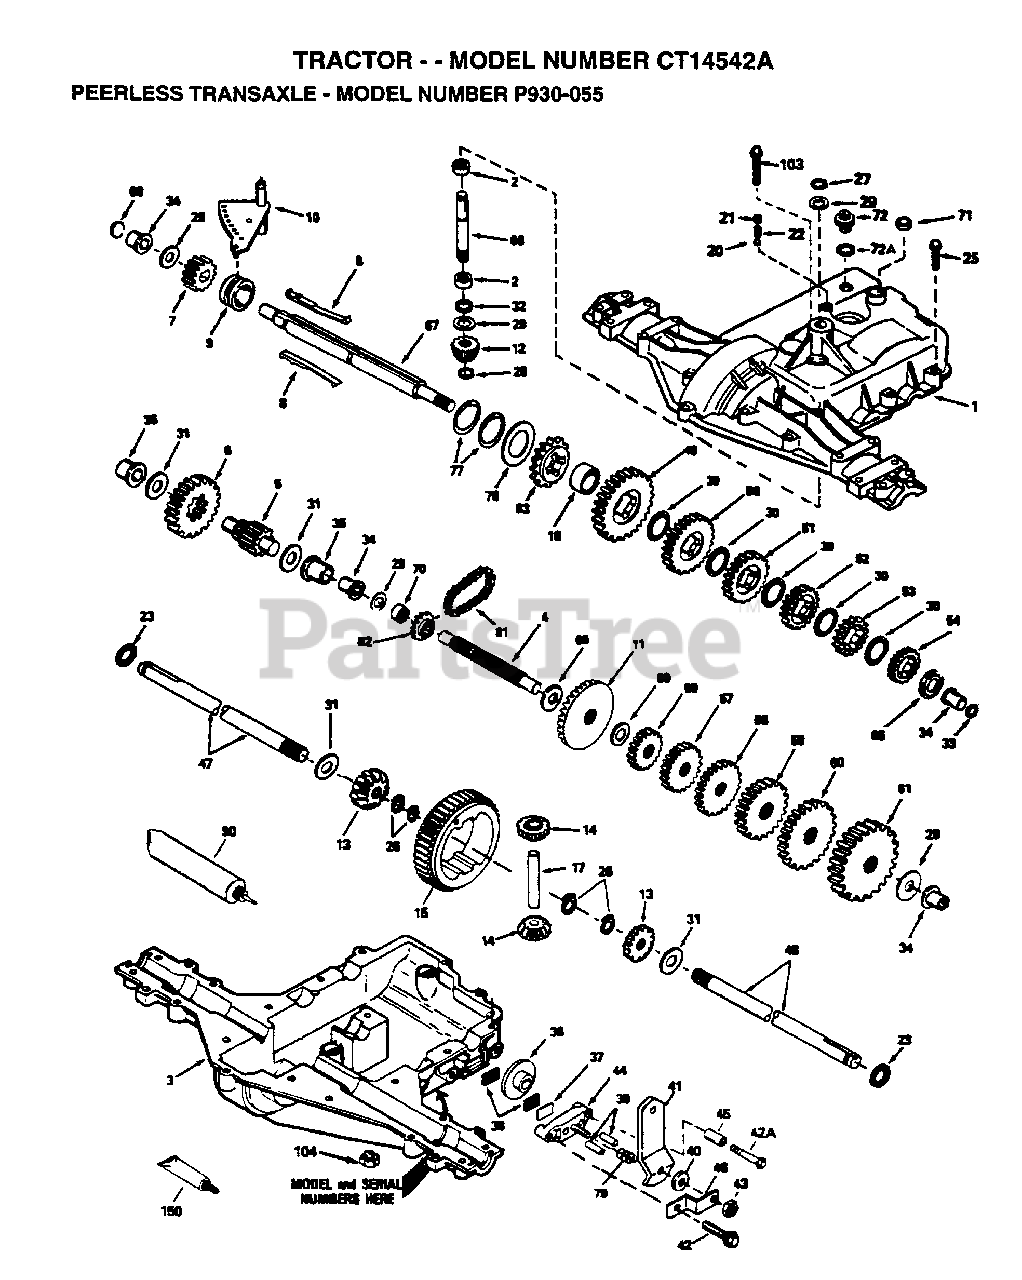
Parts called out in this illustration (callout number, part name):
1	TRANSAXLE COVER
2	BEARING, NEEDLE
3	TRANSAXLE CASE
4	SHAFT, COUNTER
5	OUTPUT SHAFT AND PINION
6	GEAR, OUTPUT
7	GEAR, SPUR, 15 TEETH
9	COLLAR, SHIFTER
10	ROD & FORK ASSY, SHIFT
11	GEAR, BEVEL, 42 TEETH
12	BEVEL PINION, INPUT
13	GEAR, BEVEL
14	GEAR, BEVEL, PINION
18	SPACER, NEUTRAL
20	BALL STEEL, 5/16" DIA.
21	SCREW, 3/8-16 X 3/8"
25	SCREW, 1/4-20 X 1-1/4
26	RING RETAINER
27	RING, RETAINER
28	RETAINING RING
29	WASHER THRUST
30	WASHER THRUST
33	SEAL, SQUARE CUT
34	BUSHING, FLANGED
35	BUSHING, FLANGED
36	DISK, BRAKE
37	PLATE BRAKE PAD
41	BRAKE LEVER
42	SCREW, 1/4-20 X 1-1/4
42A	SCREW, 1/4-20 X 2-1/4
43	LOCKNUT 5/16-24
44	HOLDER BRAKE PAD
46	BRKT BRAKE LEVER
49	GEAR, SPUR, 37 TEETH
50	GEAR, SPUR, 35 TEETH
51	GEAR, SPUR, 30 TEETH
52	GEAR, SPUR, 25 TEETH
53	GEAR, SPUR, 22 TEETH
54	GEAR, SPUR, 19T
56	GEAR, SPUR, 12 TEETH
57	GEAR, SPUR, 15 TEETH
58	GEAR, SPUR, 20 TEETH
59	GEAR, SPUR, 25 TEETH
60	GEAR, SPUR, 28 TEETH
61	GEAR, SPUR, 31 TEETH
65	WASHER, THRUST
66	SHAFT, INPUT
67	SHAFT, BRAKE, 4 KEYED
69	WASHER THRUST
71	SEAL SQUARE CUT
72	THREADED PLUG 9/16-18
76	WASHER, THRUST
77	INVERTED RETAINING RING
81	CHAIN, ROLLER
82	SPROCKET 9T
83	SPROCKET 18T (REV)
90	GREASE BENTONITE, 32 OZ.
150	GASKET ELIMINATOR
